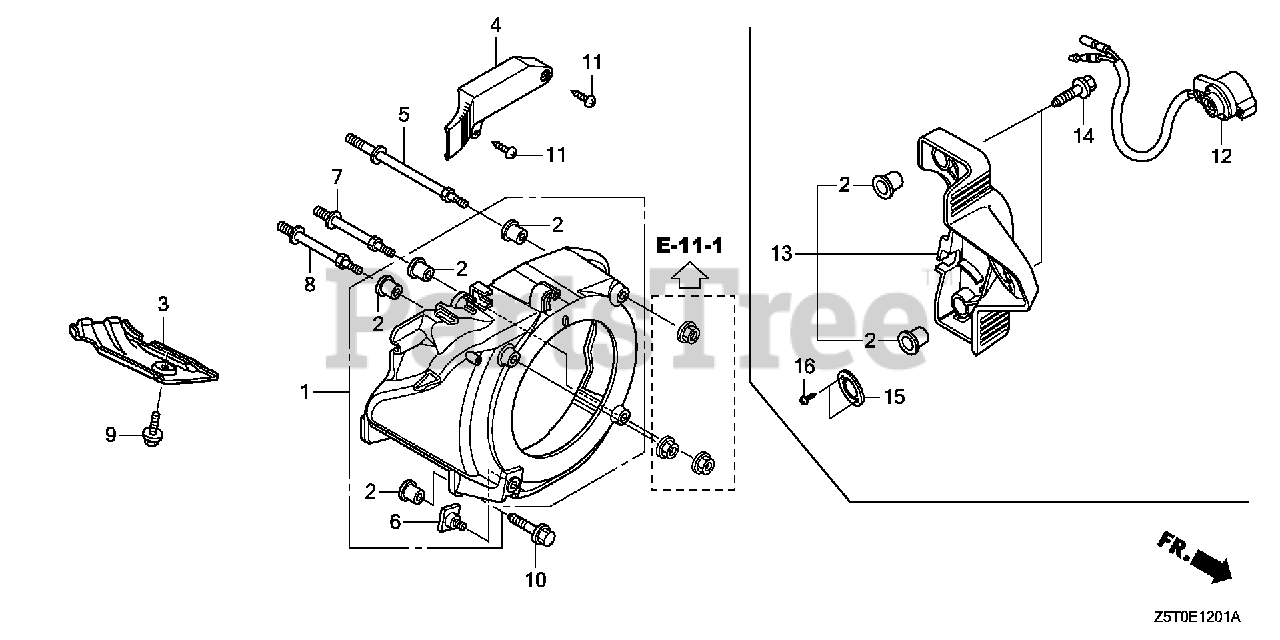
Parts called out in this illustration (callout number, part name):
1	COVER, FAN *NH1* (BLACK)
1	COVER, FAN *R280* (POWER RED)
2	COLLAR, FAN COVER (Honda Code 5580527). (N/A: SEE ASSEMBLY)
5	BOLT, STUD (SEL)
6	BOLT, SPECIAL (6MM)
7	BOLT, STUD
8	BOLT B, STUD
9	BOLT, FLANGE (6X12) (CT200)
10	BOLT, FLANGE (6X25) Use up to Engine SN 2056819.
